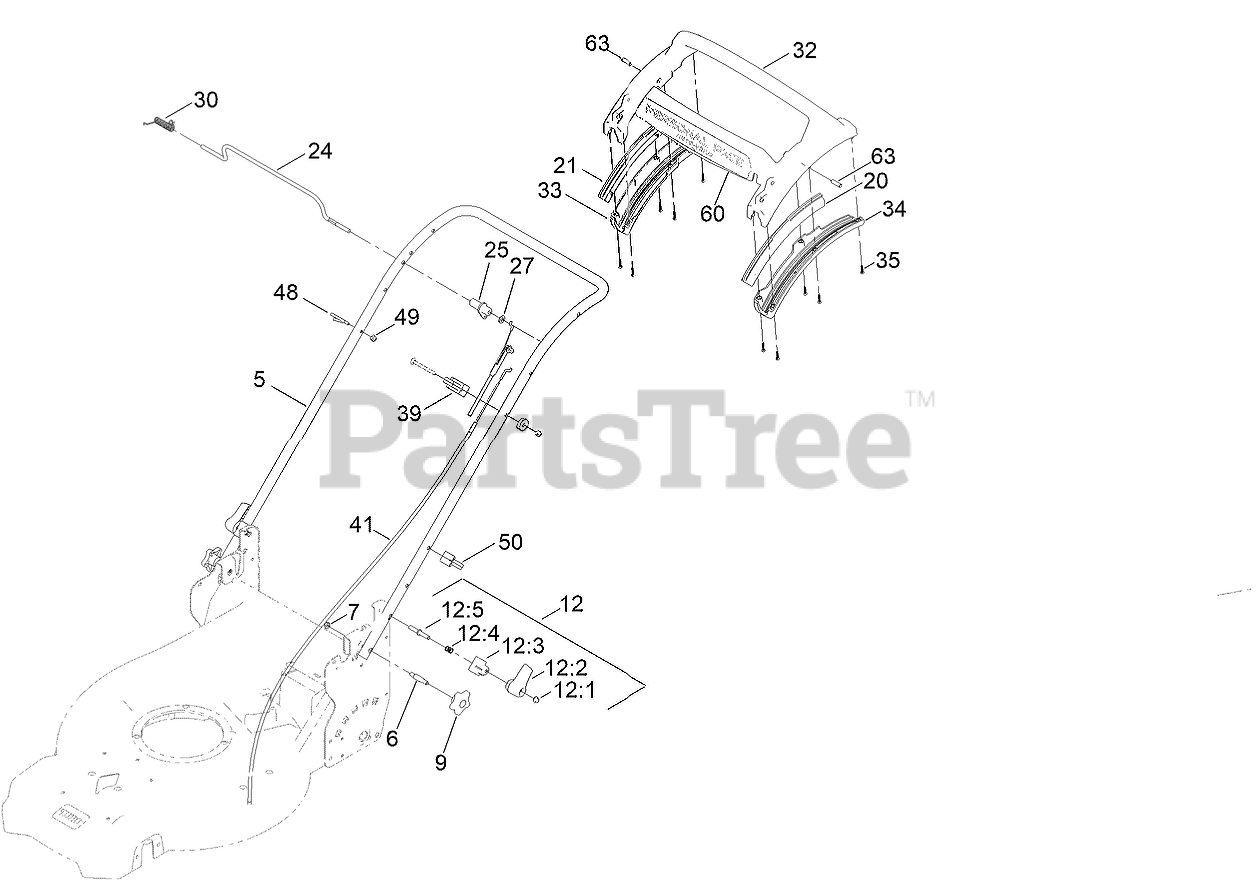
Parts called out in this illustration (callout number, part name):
5	HANDLE-CURVED
6	BOLT-SHOULDER, HANDLE
7	NUT-LOCK, NI
9	KNOB-HANDLE
12	QUICK RELEASE ASM
12:1	NUT-PUSH
12:2	LEVER-RELEASE
12:3	ANCHOR-SPRING
12:4	SPRING-COMPRESSION
12:5	ROD-RELEASE
20	GUIDE-CURVED, LH (RWD)
21	GUIDE-CURVED, RH (RWD)
24	ROD-CONTROL, TRACTION
25	LEVER-TRACTION, RWD
27	WASHER-PLAIN
30	SPRING-TORSION
32	HANDLE-PERSONAL PACE, CURVED
33	BOTTOM-HANDLE, RH
34	BOTTOM-HANDLE, LH
35	SCREW-PPH
39	ANCHOR-CABLE, RWD
41	CABLE-TRACTION, RWD (PP)
48	GUIDE-ROPE
49	NUT-HEX
50	GUIDE-CABLE
60	DECAL-HANDLE, PP
63	PIN-HANDLE, PP
